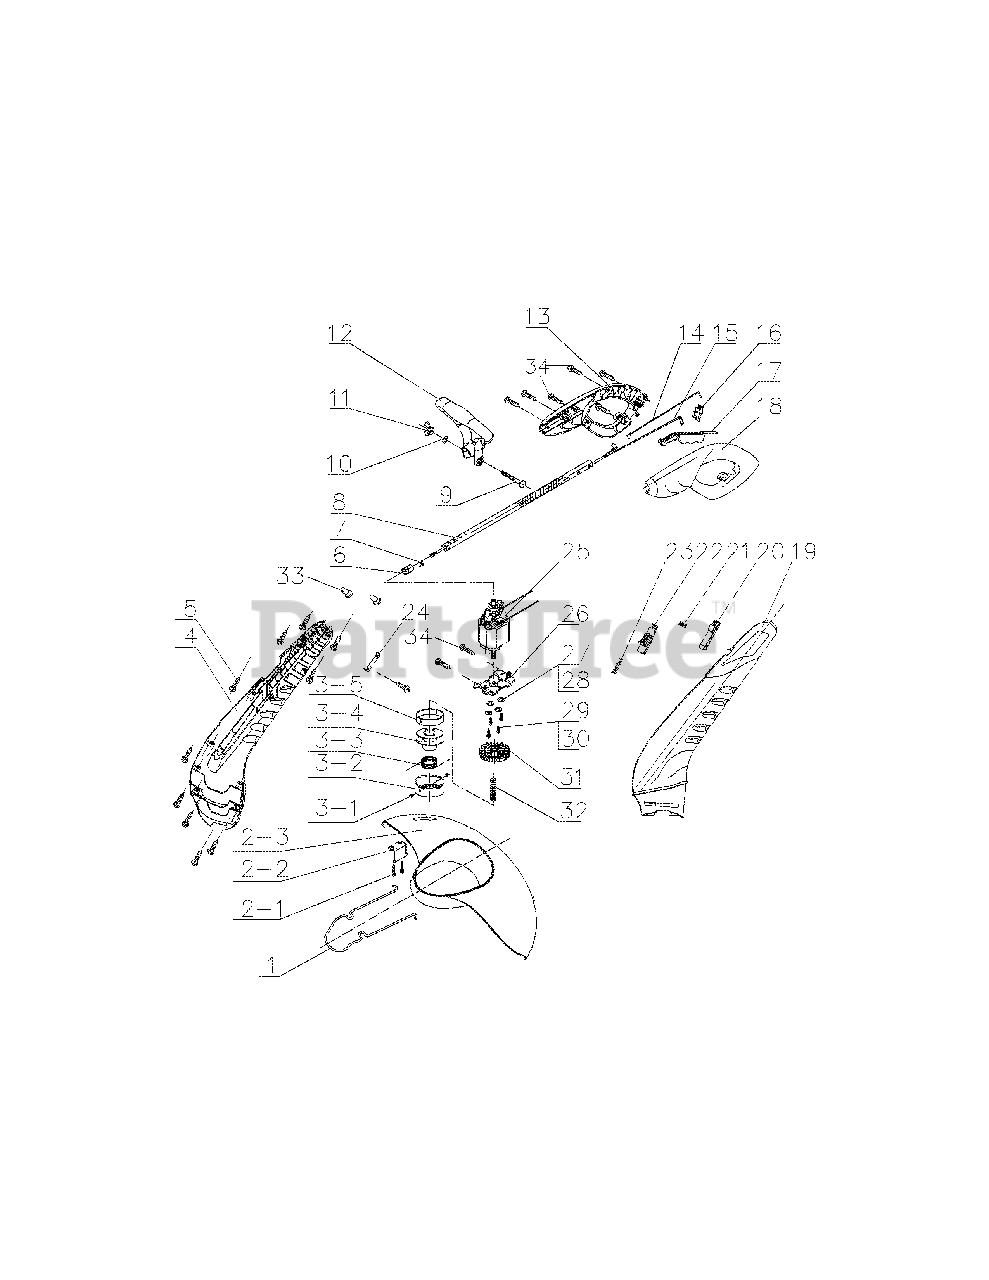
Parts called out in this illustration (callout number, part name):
1	PROJECTIVE GUARD
3	SPOOL CARRIER ASS'Y
4	HOUSING - MTD RED
7	SNAP BUTTON
8	ADJUSTABLE ROD
12	CENTRAL HANDGRIP
13	UPPER HANDGRIP MTD RED
17	TRIGGER - Black
18	UPPER HANDGRIP L - MTD RED
19	HOUSING (L)-MTD RED
22	BUTTON-Black
25	MOTOR 120V
26	MOTOR PLATE
31	CUTTER ASS'Y
33	TERMINAL BLOCK
